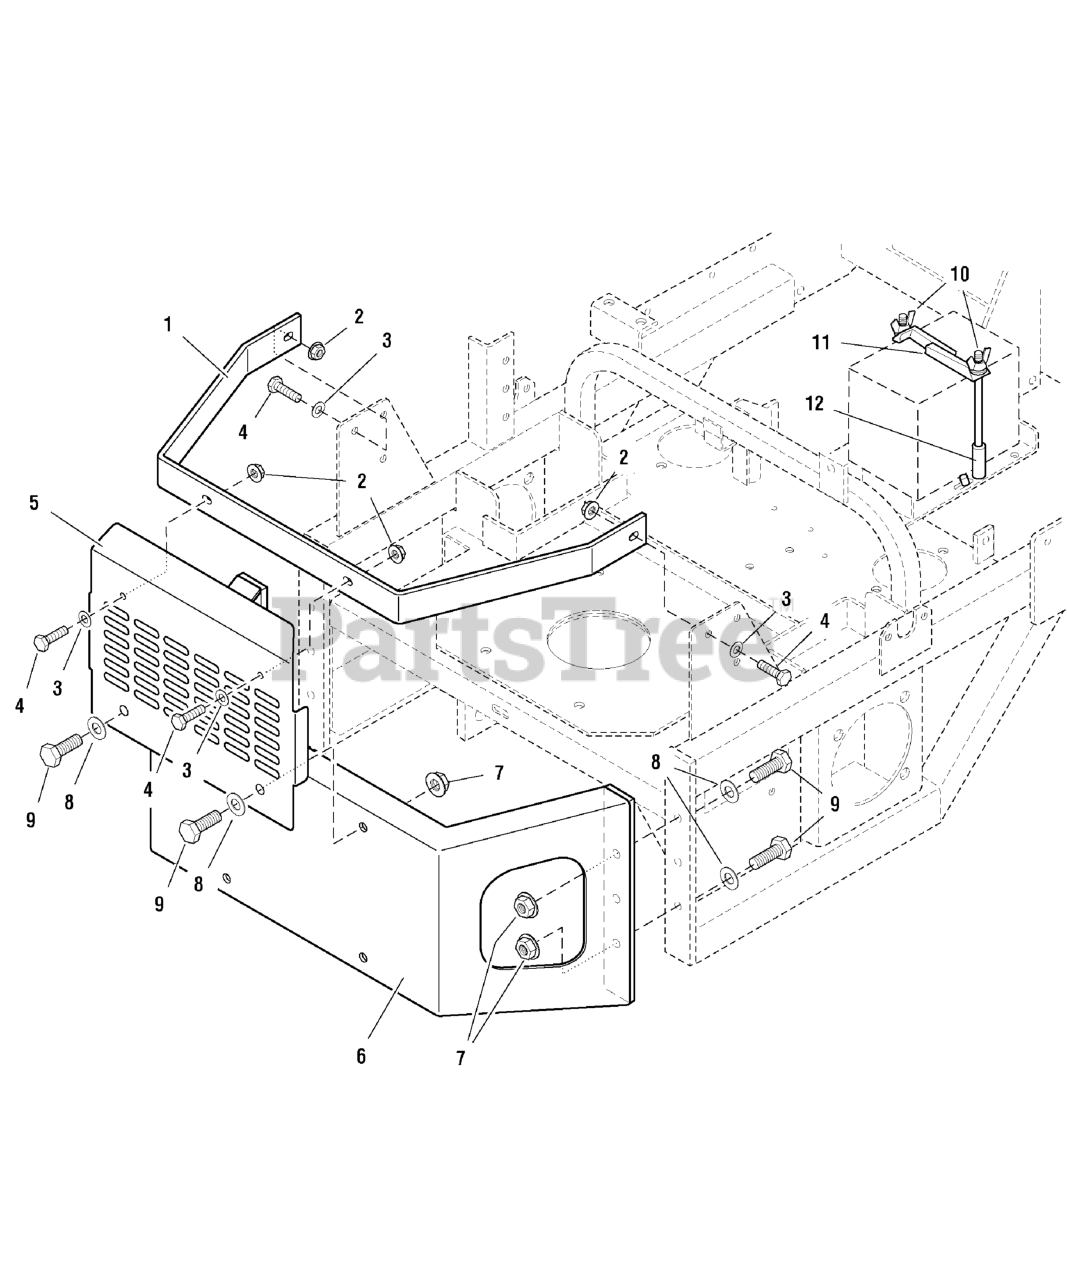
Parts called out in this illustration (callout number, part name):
1	BUMPER BAR
2	NUT, 5/16-18 HEX SERRATED FLANGE (LARGE)
3	WASHER, 5/16" SAE
4	BOLT, 5/16-18 X 1 GD5 YZ
5	BUMPER SHIELD
7	NUT, 3/8-16 Hex Serrated Flange
8	WASHER, 3/8 SAE
9	BOLT, 3/8-16 X 1" GD5 CZ
10	BATTERY HOLDDOWN BOLT
11	BATTERY HOLDDOWN
12	1/4" Fuel Line, 3" Long
